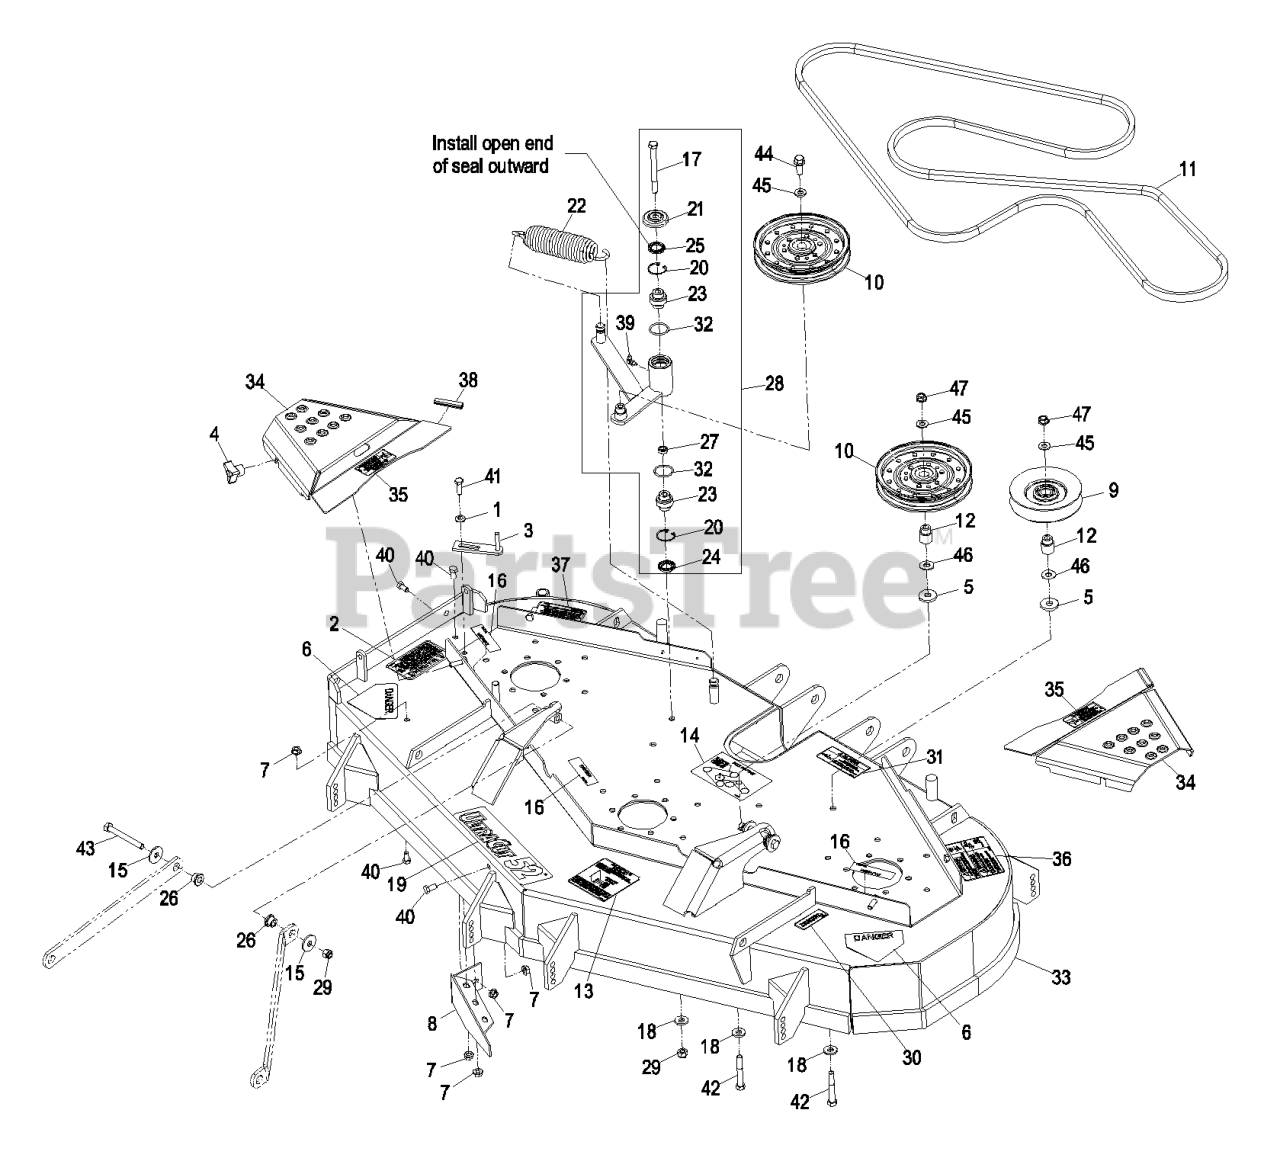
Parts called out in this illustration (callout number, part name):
1	WASHER-SPRING
2	DECAL-WARNING, DISCHARGE
3	GUIDE-BELT
4	KNOB-3 PRONG
6	DECAL-DANGER
8	WLD,BAFFLE DISCHARGE
9	PULLEY-IDLER
11	BELT,BLADE DRIVE 52
12	BUSHING-IDLER
13	DECAL,ANTISCALP
14	DECAL,BELT ROUTING
16	DECAL-COVER, MISSING
17	SCREW-HH
18	WASHER-BELLEVILLE
19	DECAL,ULTRACUT 52
20	RING-SNAP
21	GUARD-TOP
23	BEARING-SPHERICAL
24	SEAL-LIP, DOUBLE
25	SEAL-LIP, SINGLE
26	SPACER-STRUT
28	KIT,DECK IDLER LZ/XP
29	NUT-LOCK, NI
30	DECAL,BOLT TORQUE
31	DECAL-DRIVELINE
34	ASM,BELT SHIELD W/DECAL
35	DECAL,CRUSHING HAZARD
36	DECAL,DECK WARNING
37	DECAL,CRUSHING HAZARD
39	FITTING-GREASE, 90 DEG
40	SCREW-HH
41	SCREW-HH
42	BOLT-CARR
43	SCREW-HH
44	SCREW-HHF
45	WASHER-FLAT
46	WASHER-FLAT
47	NUT-HHF, WHIZ
48	ASM,FR524 DECK ASM W/DECA
